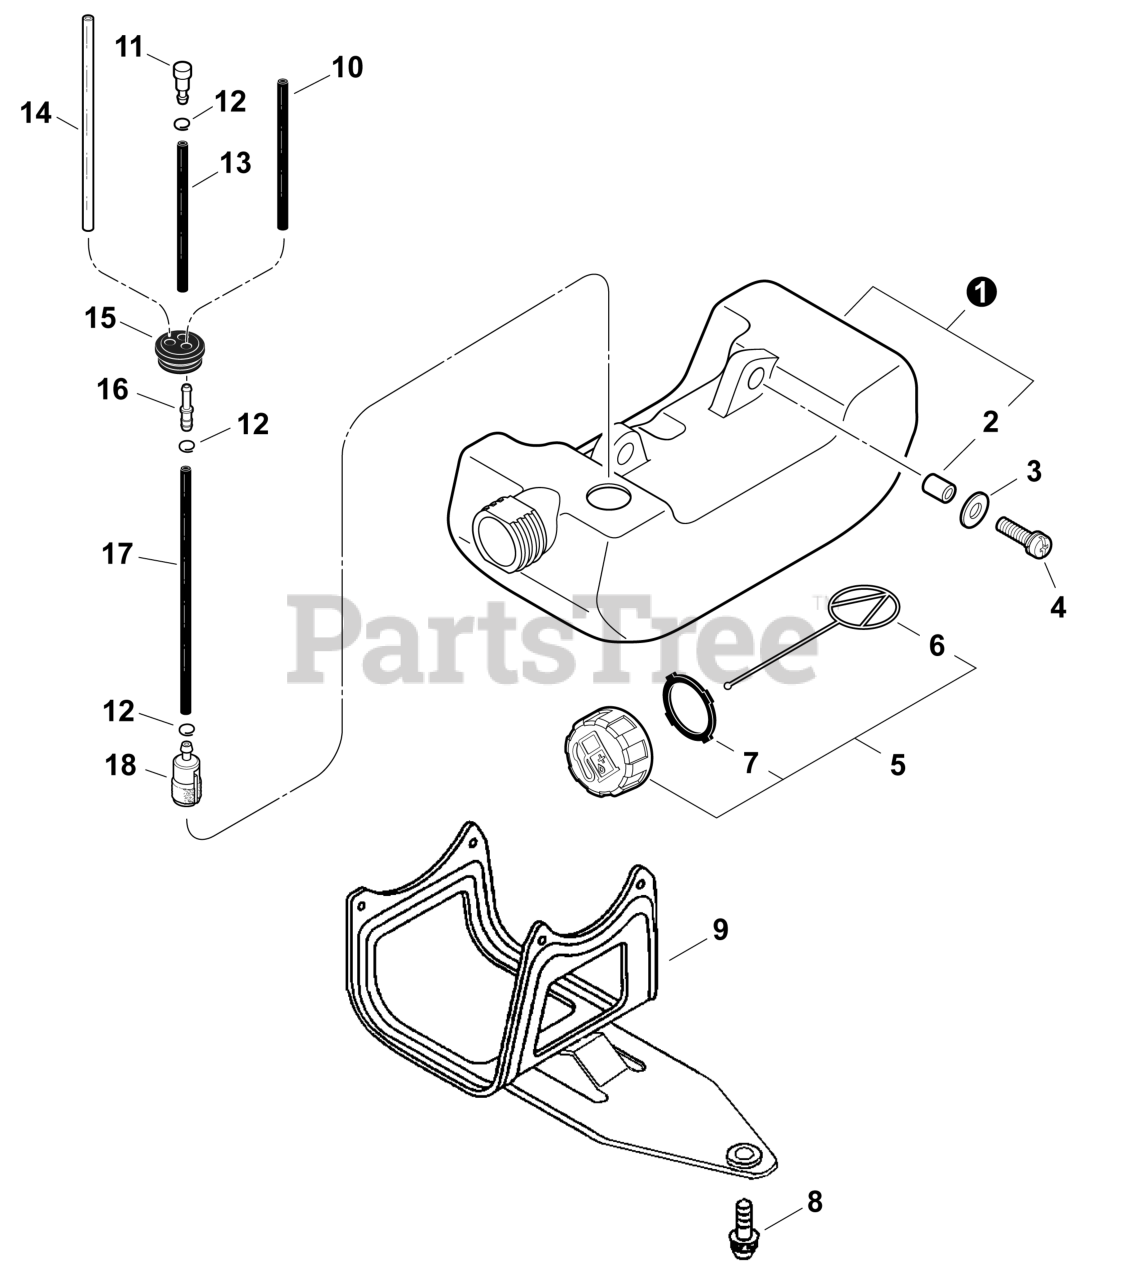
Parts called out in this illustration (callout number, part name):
1	TANK, FUEL
2	SPACER 6.2×7.8×6
3	WASHER 5.5×12×0.8
4	SCREW 5×16
5	CAP ASSY, FUEL
6	CONNECTOR, CAP L= 100 MM
7	GASKET, FUEL CAP
8	SCREW 5×16
10	PIPE, FUEL - 3×5×67 - BLACK
11	VENT ASSY
12	CLIP Ø6
13	PIPE, VENT
14	PIPE, FUEL 3×6×80 YELLOW
15	GROMMET, FUEL Ø5
16	CONNECTOR, PIPE Ø5ר3.5
17	PIPE 3×5×110
18	FILTER, FUEL
